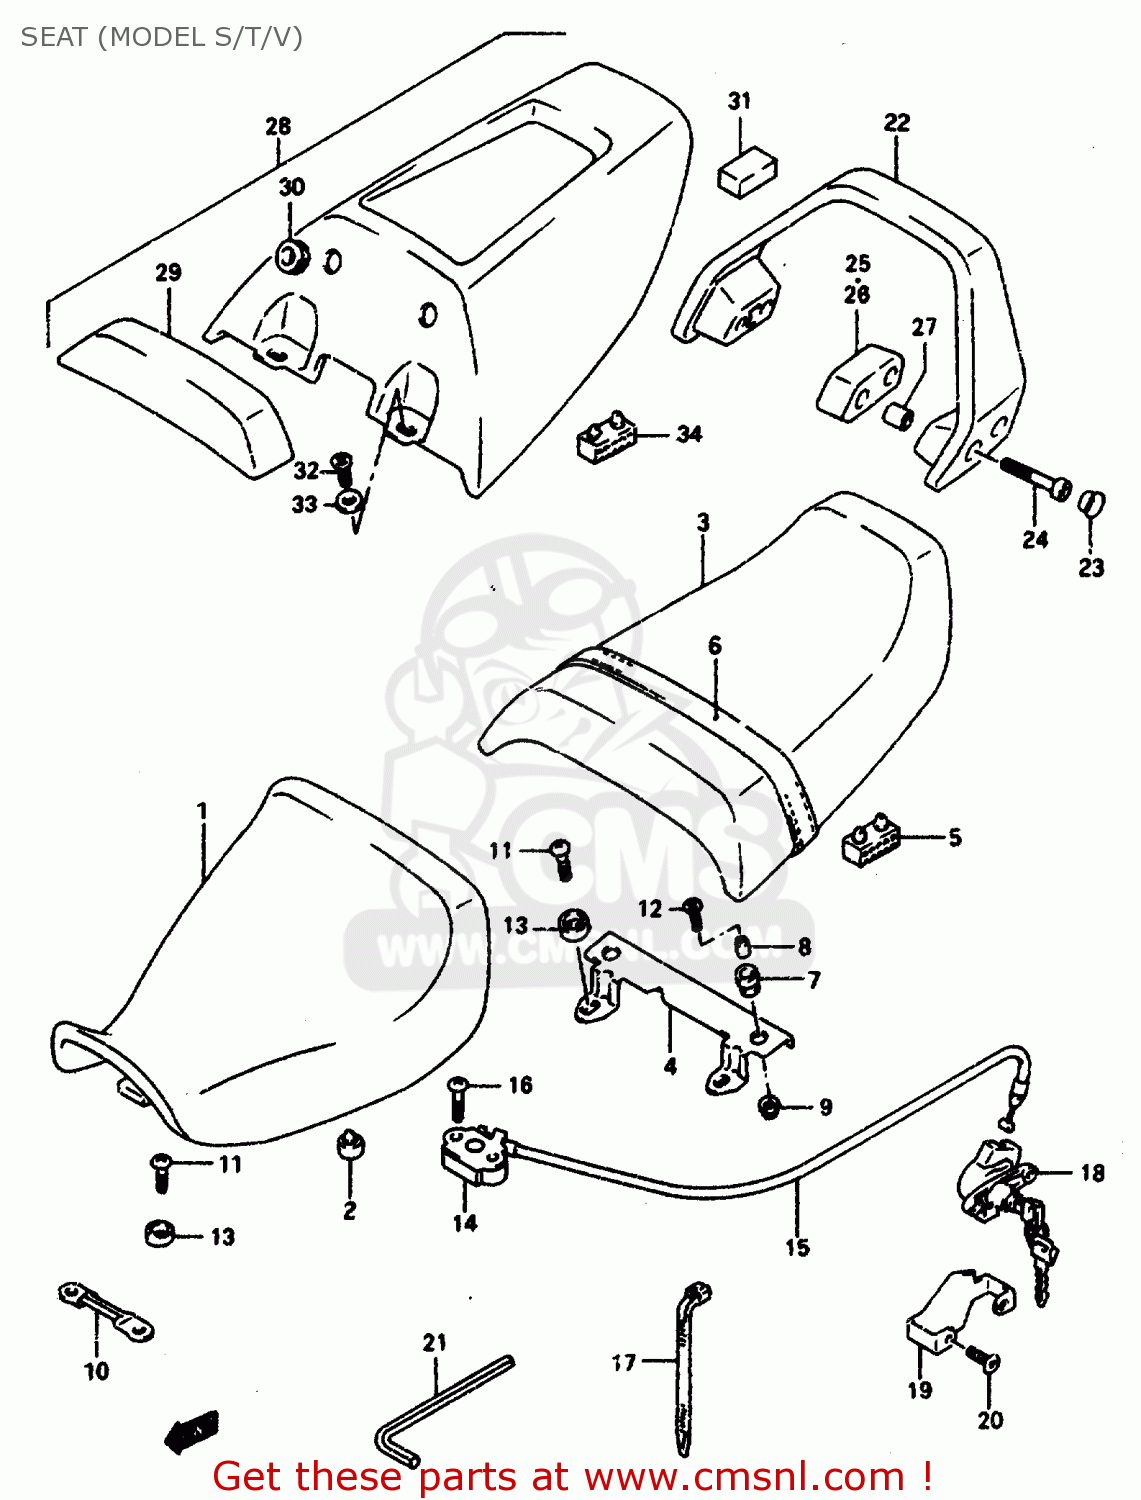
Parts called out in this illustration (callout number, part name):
1	SEAT ASSY
2	CUSHION
3	SEAT ASSY,PILL
4	PLATE,FR HOOK
5	CUSHION,SEAT(40X20X15)
6	BAND,SEAT(BLACK)
7	CUSHION
8	SPACER
9	NUT
10	PLATE,SEAT FR HOOK
11	SCREW
12	SCREW(6X12)
13	CUSHION,TAIL COVER UPR
14	BRACKET,SEAT SUPPORT RR
15	CABLE,SEAT LOCK
16	SCREW
17	CLAMP L:165
18	LOCK SET,SEAT
19	PLATE,SEAT LOCK GUARD
20	SCREW(6X12)
21	SPANNER,HEXAGON(4)
22	HANDLE,PILLION RIDER
23	CAP(OD:14.5)
24	BOLT
25	CUSHION,PILLION RIDER HANDLE,R
26	CUSHION,PILLION RIDER HANDLE,L
27	SPACER (8.5X16X37)
28	BOX SET,SEAT TAIL
29	BACKREST,SEAT(BLACK)
30	CUSHION
31	PROTECTOR,TAIL BOX
32	SCREW(6X16)
33	WASHER(6.5X20X1.6)
34	CUSHION,SEAT(40X20X15)
